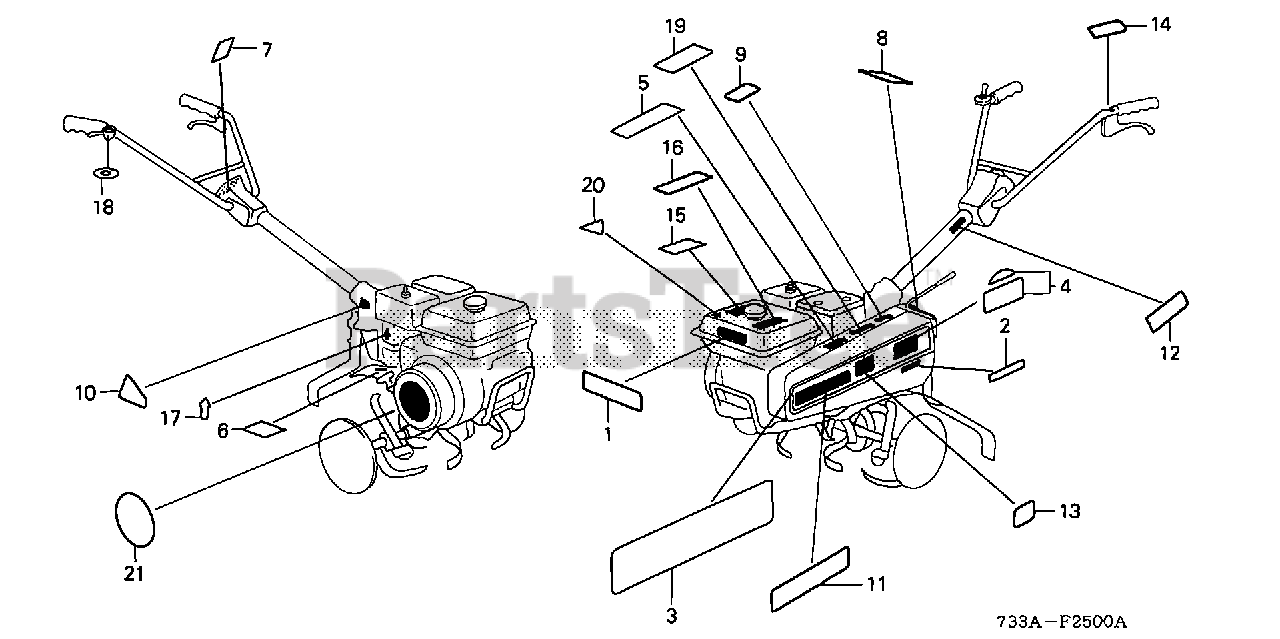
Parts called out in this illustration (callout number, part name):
7	MARK, SWITCH (ENGLISH) (NOT AVAILABLE)
9	CAUTION, BELT COVER (ENGLISH)
10	CAUTION, OPERATOR (ENGLISH)
11	MARK, BELT COVER
12	LABEL, WARNING (ENGLISH)
13	CAUTION, BELT ADJUSTING
14	CAUTION, CLUTCH LEVER (ENGLISH) (NOT AVAILABLE)
16	MARK A, CAUTION (ENGLISH/FRENCH)
17	MARK, CHOKE
21	MARK, HONDA (D)
